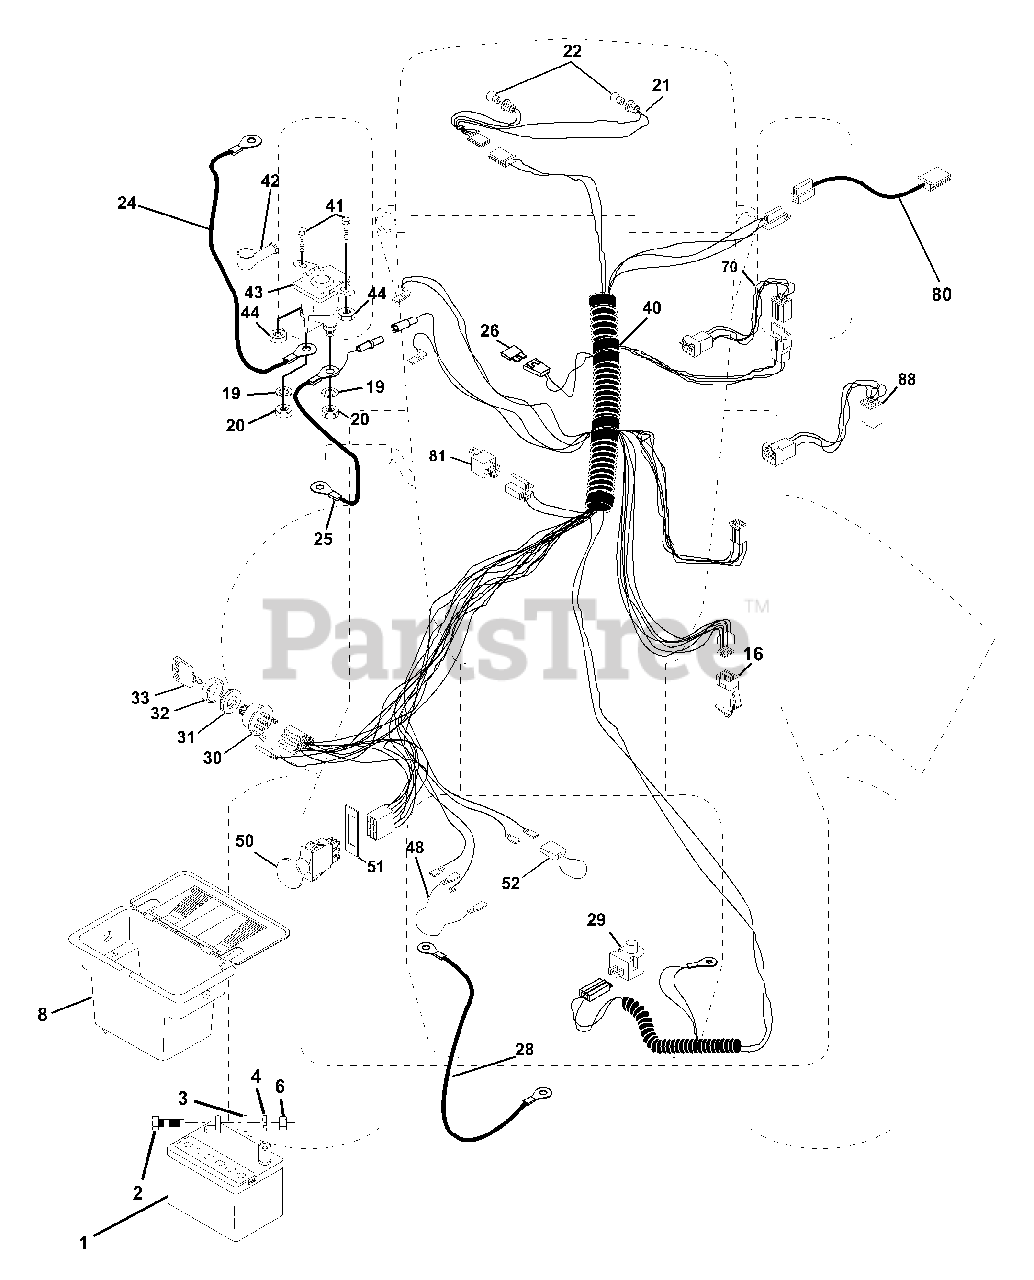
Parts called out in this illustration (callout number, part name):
1	Battery 12 Volt 25 AMP
2	Bolt Hex Hd 1/4-20unc X 3/4
3	Washer 9/32 X 5/8 X 16 Ga.
4	Washer Lock Hvy Helical 1/4
6	Nut Fin Hex 1/4-20 Unc
8	Case Battery Mech Hinge
16	Switch Interlock Push-In
19	Washer Lock 1/4
20	Nut Jam Hex 1/4-20 Unc
21	Harness Asm Light W/4152j
22	Bulb Light #1156
24	Cable Battery 6 Ga 11" red
25	Cable Battery 6 Ga 44" red w/16 wire
26	Fuse 30 AMP Auto Green
28	Cable Ground 6 Ga 12" black
29	Switch Plunger Normal OP Olive
30	Switch Ign 4 pos w/lights
31	Nut Ignition
32	Cover Sw Ignition
33	Key Ign Modelled Generic
40	Harness Ign.
41	Bolt Blk Fin Hex 1/4 - 20 x 1/2
42	Cover Terminal Red
43	Solenoid
44	Nut Keps Hex 1/4-20 Unc
48	Adapter Ammeter Rectangular
50	Switch PTO 3PDT Black Delta 96
51	Ring Retainer PTO
52	Protection Wire Loop
70	Harness, Eng. kohl Cmd-L Dual
80	Harness Clutch EVX
88	Harness Eng Koh Cv15 Stator
